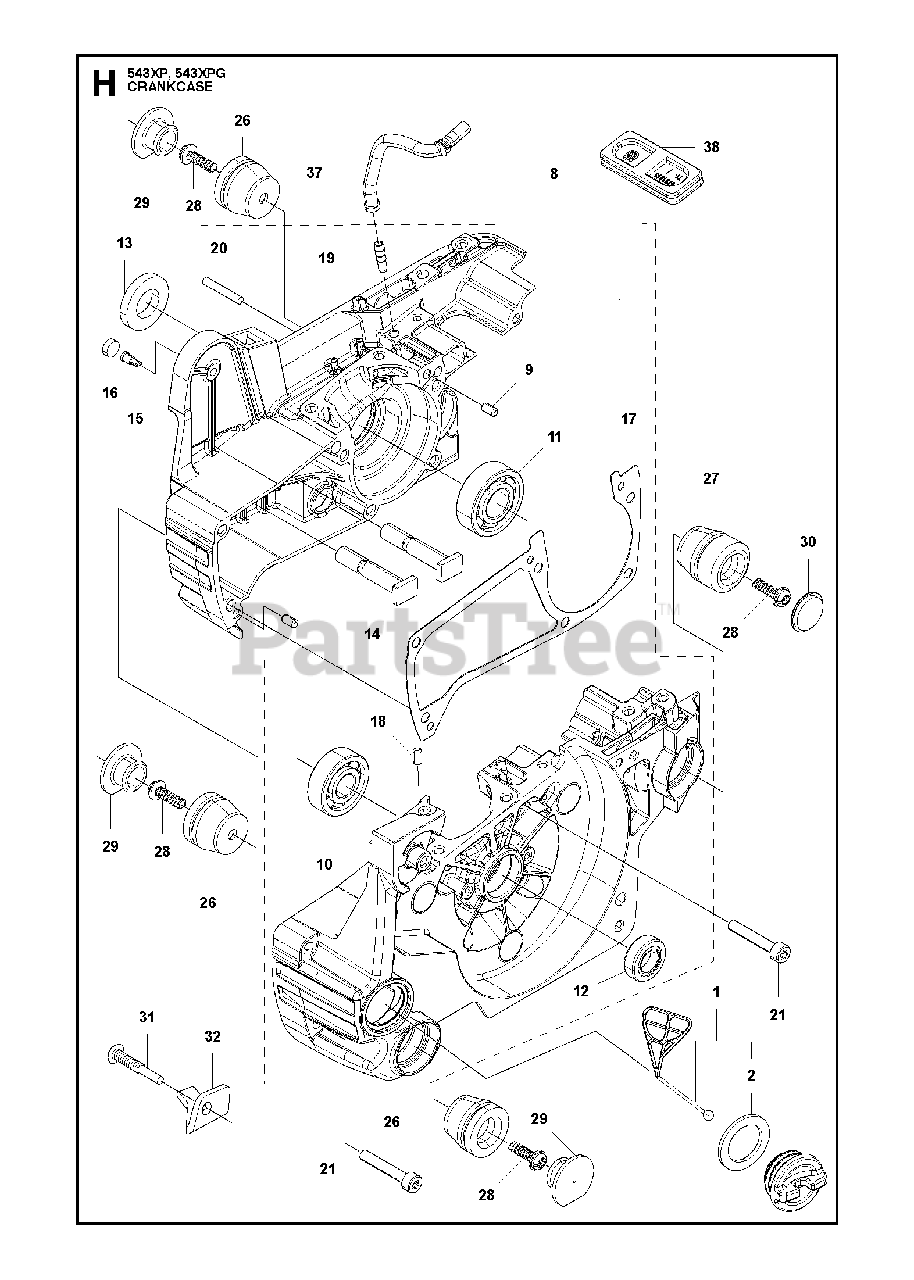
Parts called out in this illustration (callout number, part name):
1	CAP ASSY 848C1H8610
2	GASKET
8	CRANKSHAFT ASSY
10	BEARING Z285021240
11	BEARING
12	SEAL
13	SEAL
14	BOLT
15	AIR CONTROL BREATHER
16	SEAL Z285021250
17	GASKET, CRANKCASE
18	PIN XC23
19	FITTING PULSE XC23
20	PIN 8488B42400
21	BOLT
27	DAMPER T210035210
28	SCREW
31	SCREW T27 XC23
32	CHAIN CATCHER
